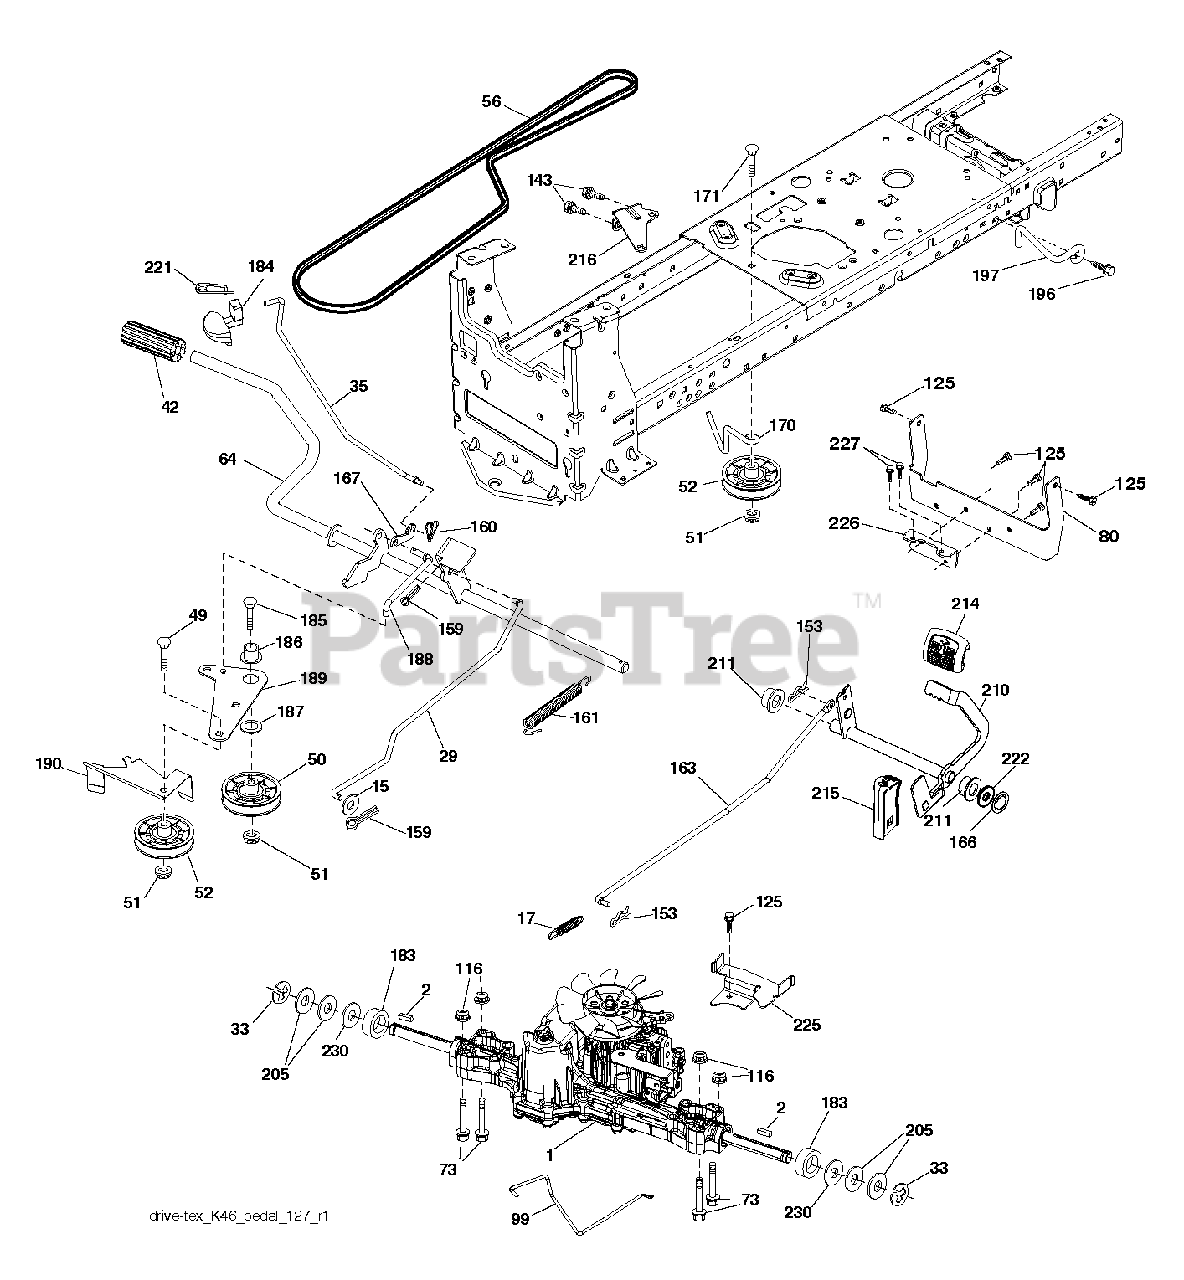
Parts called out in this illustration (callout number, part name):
2	SQUARE KEY
15	WASHER
17	SPRING.BRAKE.K46.GREEN
29	ROD.BRAKE.K46
35	ROD .BRAKE. PARKING. GT. HUSQ.
42	PEDAL COVER T
50	IDLER.FLAT.910.OFFSET
51	NUT LOCK FLG 3/8-16 UNC
52	IDLER.V-GROOVE.910.OFFSET
56	V-BELT.MOWER.92.40.42/K46
64	SHAFT.ASM.PEDAL.BRK.CNTR
80	STRAP.TORQUE.K46.K57R.TT
99	ROD.SPRING.BYPASS.K46.LT.Z
116	NUT LOCK HEX FLANGE 5/16-18
125	SCREW
143	SCREW LT
153	RETAINER M
159	COTTER PIN
160	RETAINER CLIP
161	SPRING, RETURN LT
163	ROD.CONTROL.K57R.K46
166	NUT.PUSH.625
167	LATCH.BRAKE.SPRING
170	KEEPER.V-IDLER.CENTER.
183	SPACER AXLE
184	HANDLE.PARKING.BRAKE.H (BLK)
186	SPACER.RETAINER
187	WASHER 12/32X2X10GA
188	RP LINK.CLUTCH.GROUND.DRIVE
189	BELLCRANK.GROUND.DRIVE.TEX.
190	KEEPER.BELLCRANK.DRIVE
196	SCREW 3/8-16X1
197	LINK.CLUTCH.ANIT-ROTAT
210	ROCKER.ASM.PEDAL.CONTR
211	BEARING.NYLON
214	PEDAL.FORWARD.PAD.TEX
215	PEDAL.COVER.REVERSE.CRD.X498GY
216	BRACKET.PULLEY.IDLER.W/TEX
221	RETAINER.SPRING.CLIP.H
222	WASHER 21/32 X 1-1/4 X 10 GA.
225	KEEPER.BELT.TRANSAXLE.K46
226	BRACKET.MOUNT.TORQUE.K46.TLT
227	SCREW
230	WASHER.HARDENED
